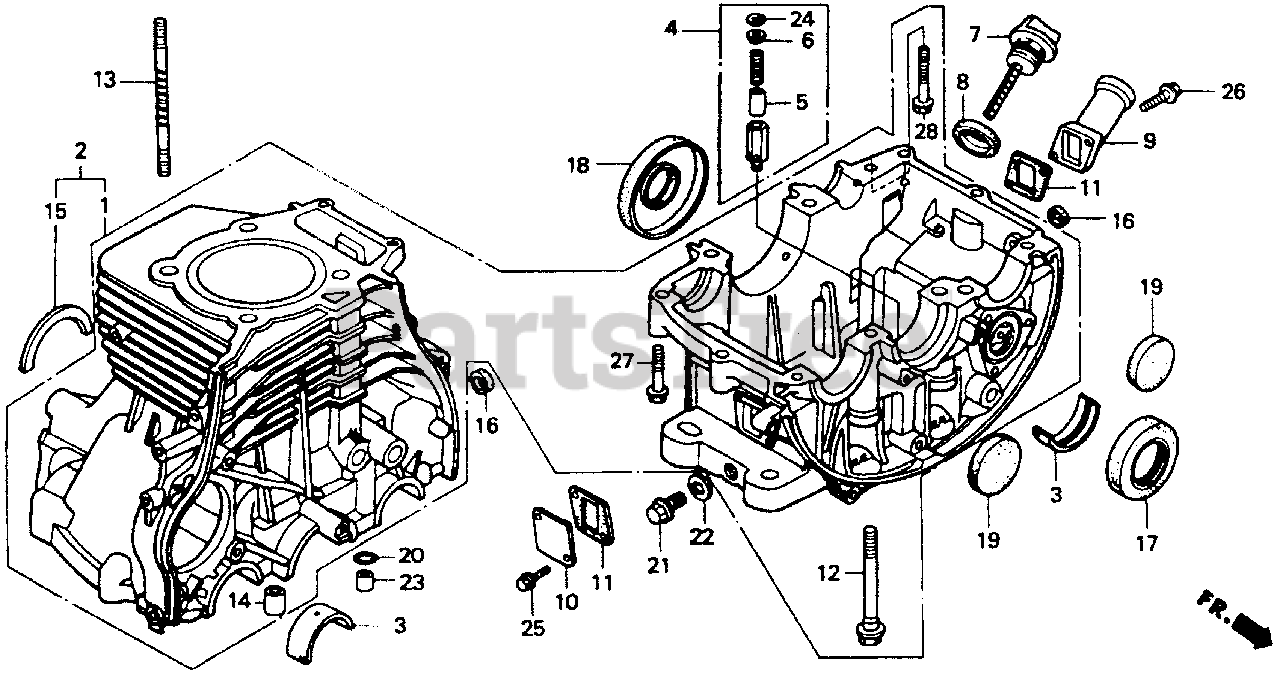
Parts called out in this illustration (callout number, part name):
1	CYLINDER ASSY. (Q-TYPE)
3	BEARING A, MAIN (BLUE)
3	BEARING B, MAIN (BLACK)
3	BEARING C, MAIN (BROWN)
3	BEARING D, MAIN (GREEN)
3	BEARING E, MAIN (YELLOW)
3	BEARING F, MAIN (PINK)
3	BEARING G, MAIN (RED)
3	BEARING A, MAIN (US 0.25) (BLACK)
3	BEARING B, MAIN (US 0.25) (BROWN)
3	BEARING C, MAIN (US 0.25) (GREEN)
3	BEARING A, MAIN (US 0.75) (BLACK)
3	BEARING B, MAIN (US 0.75) (BROWN)
3	BEARING C, MAIN (US 0.75) (GREEN)
4	VALVE ASSY., RELIEF (NOT AVAILABLE)
5	VALVE, RELIEF
6	SEAT, RELIEF VALVE
7	CAP, OIL FILLER
8	GASKET, OIL FILLER CAP
9	EXTENSION, OIL FILLER
10	PLATE, EXTENSION
11	GASKET, EXTENSION OIL FILLER (NON-ASBESTOS)
12	BOLT-WASHER (11X115)
13	BOLT, STUD (10X103.5)
14	PIN, DOWEL (13X20)
15	SET-RING (80)
16	OIL SEAL (8X14X5)
17	OIL SEAL (37X64X10)
18	OIL SEAL (31X80X10)
19	PLUG, SEAL (47MM)
20	O-RING (9.8X1.9)
21	BOLT, DRAIN PLUG (14MM)
22	WASHER, DRAIN PLUG (14MM)
23	PIN A, DOWEL (10X16)
24	CIRCLIP (INNER) (12MM)
25	BOLT, FLANGE (6X16)
26	BOLT, FLANGE (6X22)
27	BOLT, FLANGE (8X40)
28	BOLT, FLANGE (8X50)
